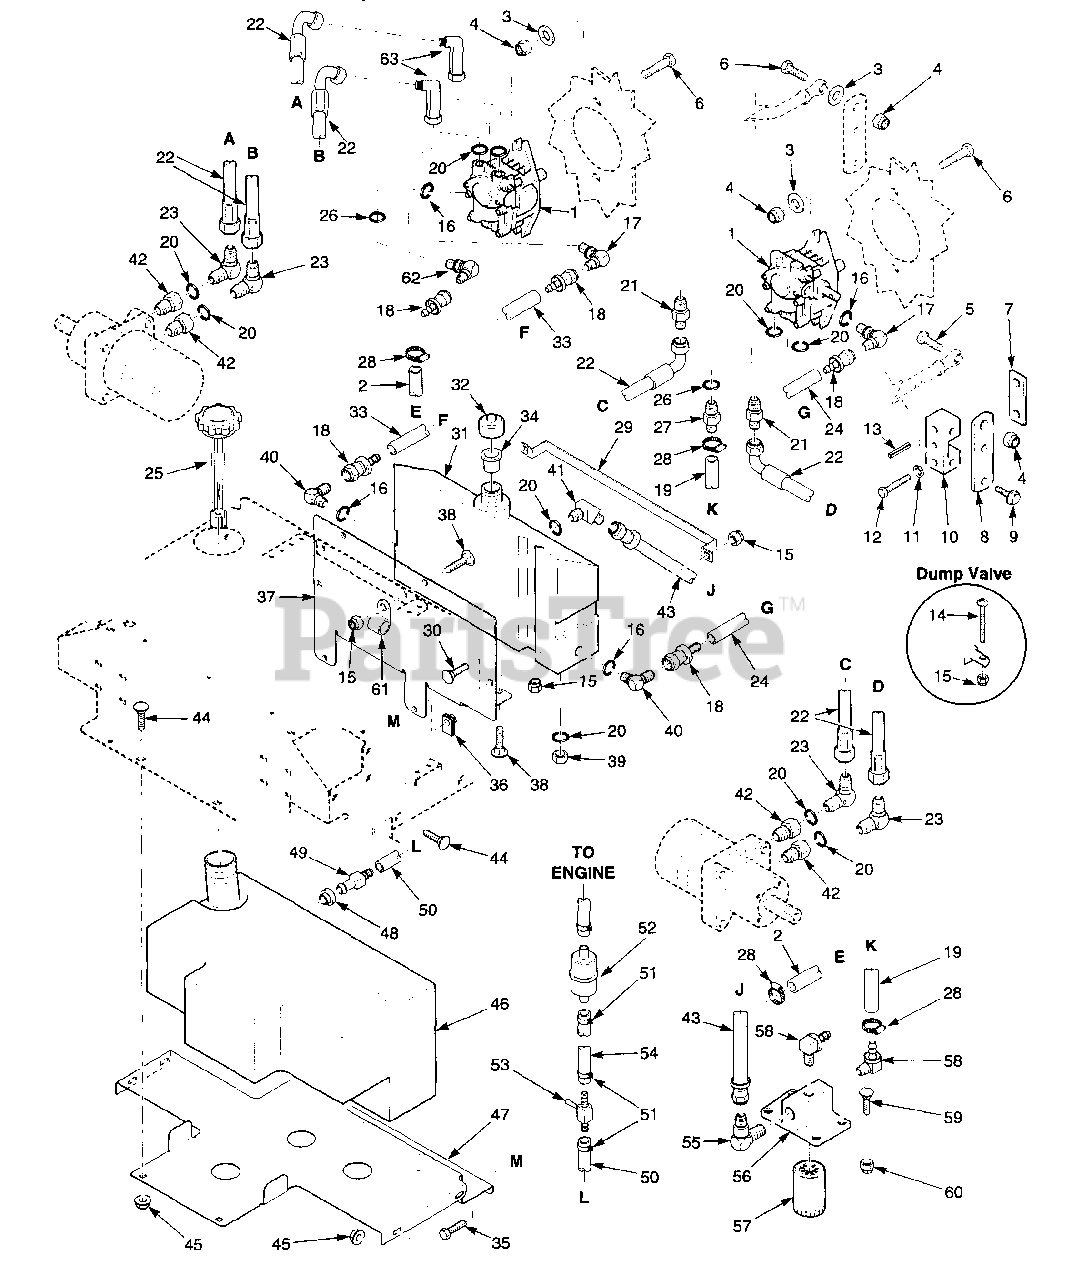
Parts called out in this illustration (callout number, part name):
1	Pump, Sunstrand BDP-10L117
2	Hose, 3/8" ID. Pushlock
3	Flatwasher, 3/8" (.391 x .938 x .105) Grade 8
4	Nut, Hex Elastic Stop 3/8-16
5	Bolt, Hex Head 3/8-16 x 1-1/4"
6	Bolt, Hex Head 3/8-16 x 1-1/2"
7	Clamp Plate, Pump Control
8	Lever, Control
9	Screw, Hex Serrated Flange 1/4-20 x 3/4"
10	Block, Pump Control
11	Lockwasher, 1/4" Spring
12	Bolt, Hex Head 1/4-20 x 1-1/4"
13	Roll Pin, Spring 3/16 x 3/4"
14	Screw, Phillips RD. Head 1/4-20 x 2"
15	Nut, Hex Elastic Stop 1/4-20
16	O-Ring
17	Elbow, 90 Degree
18	Coupling
19	Hose, 3/8" ID Push Lock
20	O-Ring
21	Union, 3/4-16 JIC x 3/4-16 O-Ring
22	Hose Assembly, Pump
23	Elbow, 90 Degree 3/4-16 JIC x 3/4-16 O-Ring
24	Hose, 3/8" ID. Pushlock
25	Cap, Fuel Tank W/Gauge
26	O-Ring
27	Connector, 7/16" O-Ring x Hose Barb
28	Clamp, Hose 1/2"
29	Strap, Hydraulic Tank
30	Bolt, Carriage 1/4-20 x 1"
31	Oil Reservoir Assembly
32	Cap, Hydraulic Tank
33	Hose, 3/8" ID. Pushlock
34	Insert, Filler Neck
35	Bolt, Hex Head 1/4-20 x 3/4"
36	U-Nut, 1/4-20
37	Support Bracket, Hydraulic Tank
38	Bolt, Carriage 1/4-20 x 3/4"
39	Plug, 3/4-16 "O" Ring
40	Elbow, 90 Degree 9/16-18 JIC x 9/16 O-Ring
41	Elbow, 45 Degree 3/4-16 JIC x 3/4-16 O-Ring
42	Bushing, 7/8-14 JIC x 3/4-16 O-Ring
43	Hose Assembly, 1/2" ID
44	Bolt, Carriage 5/16-18 x 3/4"
45	Nut, Hex Serrated Flange 5/16-18
46	Fuel Tank Assembly
47	Support Bracket, Fuel Tank
48	Bushing
49	Hose Fitting
50	Fuel Hose, 1/4" ID.
51	Clamp, Fuel Hose
52	Fuel Filter
53	Valve, Shutoff
54	Fuel Hose, 1/4" ID.
55	Elbow, 45 Degree-1/2 NPT x 3/4 JIC
56	Oil Filter Base
57	Oil Filter
58	Elbow, 90 Degree-1/4 NPT x 3/8 Hose
59	Bolt, Carriage 5/16-18 x 1"
60	Nut, Hex Elastic Stop 5/16-18
61	Hose Clamp
62	Elbow, 90 degree - 9/16 x 7/16 o-ring
63	Elbow, 90 degree LG - 3/4-16 o-ring
